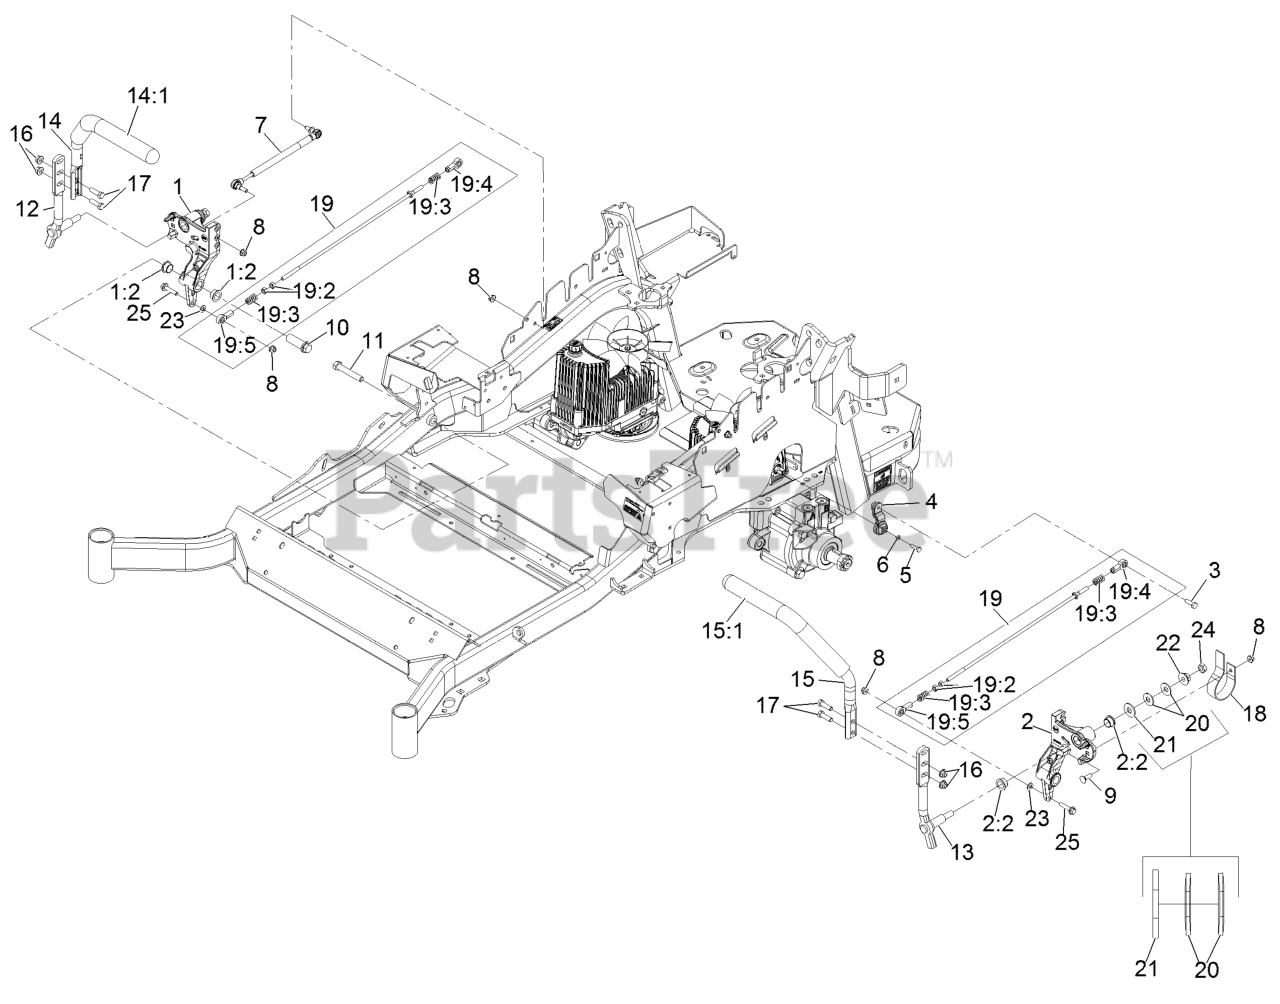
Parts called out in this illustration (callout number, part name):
1	RH MOTION CONTROL AND BUSHING ASM
1:2	BUSHING-FLANGE
2	LH MOTION CONTROL AND BUSHING ASM
2:2	BUSHING-FLANGE
3	SCREW-HH, THREAD LOCKING
4	ARM-CONTROL, PUMP
5	SCREW-HH
6	WASHER-SPRING
7	DAMPER-CONTROL, MOTION
8	NUT-HF, NI
9	BOLT-CARR
10	HUB-THREADED
11	SCREW-HH
12	LEVER-CONTROL MOTION, RH
13	LEVER-CONTROL MOTION, LH
14	RH STEERING HANDLE ASM
14:1	GRIP-LEVER, CONTROL
15	LH STEERING HANDLE ASM
15:1	GRIP-LEVER, CONTROL
16	NUT-HF, NI
17	SCREW-HH
18	SPRING-LEAF
19	FRONT PUMP LINKAGE ASM
19:2	NUT-HEX
19:3	SPRING-COMPRESSION
19:4	BALLJOINT-LH
19:5	BALLJOINT-RH
20	WASHER-SPRING
21	WASHER-FLAT
23	WASHER-PLAIN
24	NUT-JAM
25	SCREW-HHF
